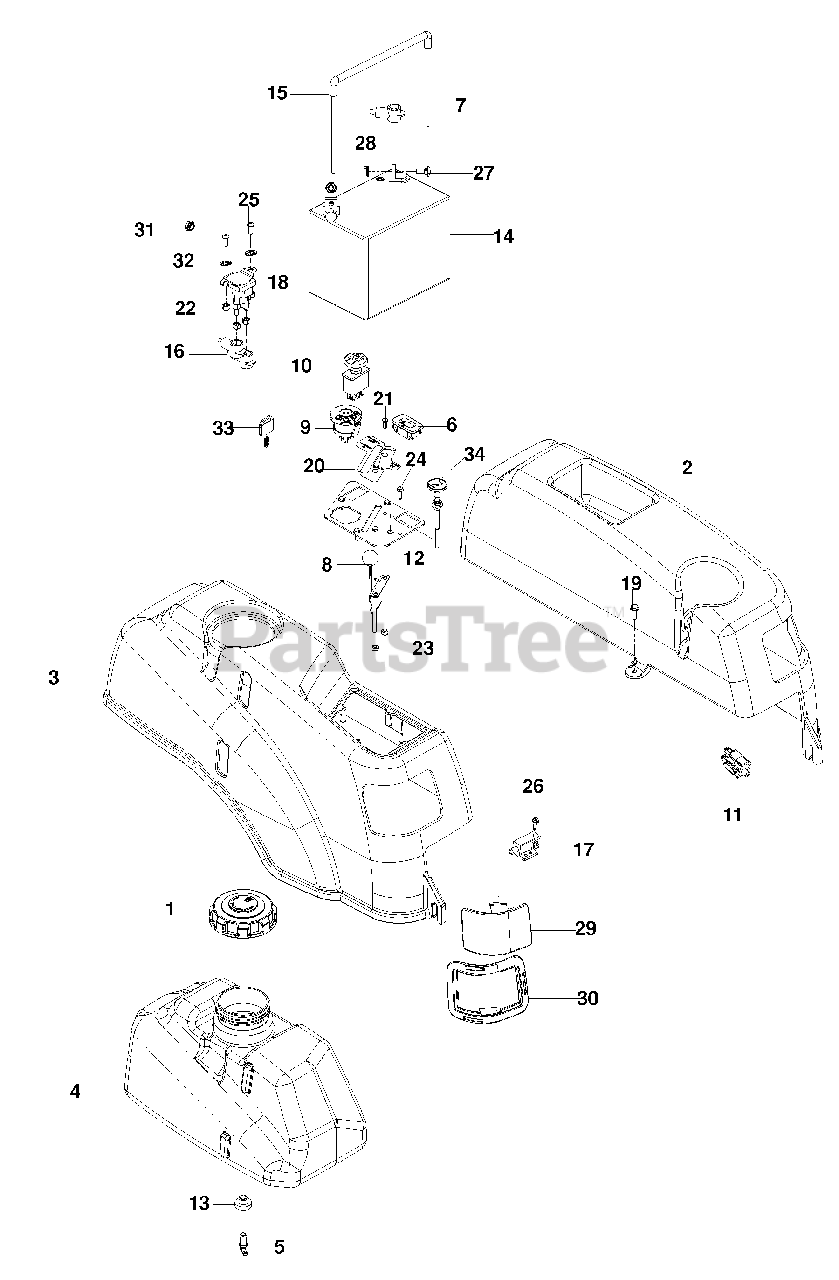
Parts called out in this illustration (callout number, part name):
2	FENDER, LT
3	FENDER, RT
4	TANK, FUEL
5	ELBOW, TANK
6	HOUR METER
7	COVER, TERMINAL
8	CABLE, THROTTLE
9	SWITCH, IGNITION
10	SWITCH, CLUTCH
11	SWITCH, BRAKE
12	PLATE, CONSOLE
13	GROMMET, RUBBER
14	BATTERY
15	TIE DOWN, BATTERY
16	COVER, TERMINAL
17	SWITCH, N.C.
19	BOLT 1/4-20 x 1/2 HWST
20	DECAL, CONSOLE
21	SCREW 10-24 x 1/2 SLT HD
22	NUT 1/4-20 HEX NYLOC
23	NUT 10-24 HEX NYLOC
24	SCREW 10-12 x 3/4 WSHR HD
25	SCREW 1/4-20 x 5/8 BTN SKT
26	SCREW 10-24 x 5/8 WSH HD
27	RHSNB 5/16-18 x 3/4
28	NUT 5/16-18 FLANGE NYLOC
29	LENS, LT
30	LENS RIM, LT
31	NUT 1/4-20 HEX NYLOC THIN
32	WASHER 1/4 ITLW
33	KEY, IGNITION
34	CONTROL, CHOKE
